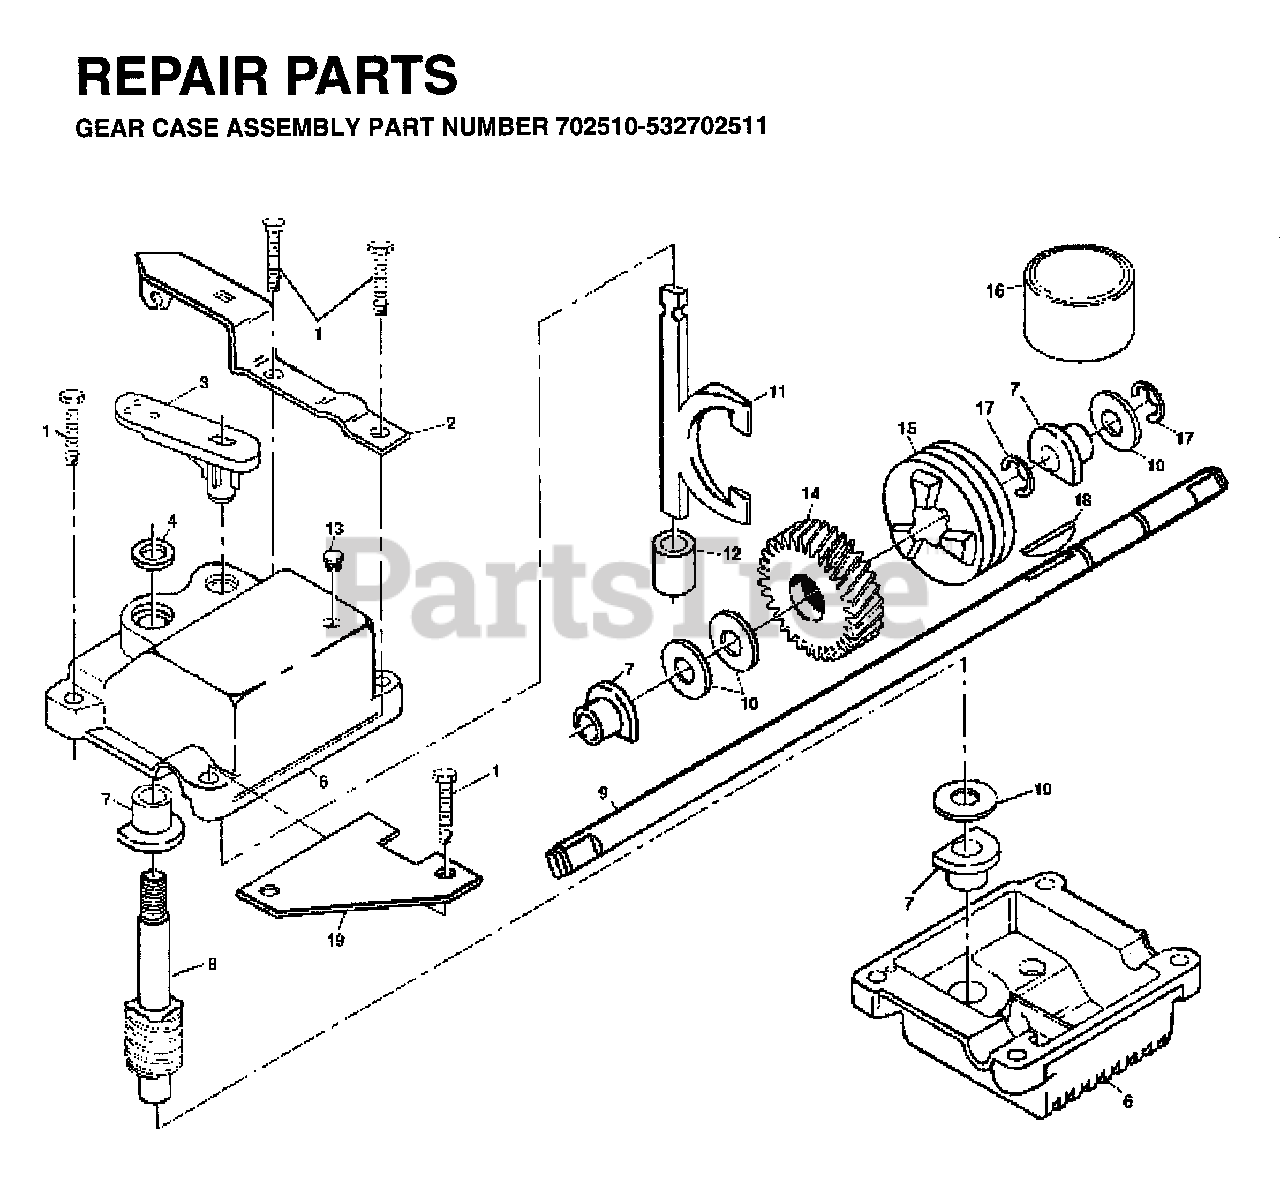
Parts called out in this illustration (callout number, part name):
1	SCREW
2	BRACKET
6	GEAR CASE
8	WORM SHAFT
9	DRIVE SHAFT, 20-5/8"
10	THRUST WASHER
11	YOKE CLUTCH
14	GEAR.HELICAL
15	CLUTCH JAW
16	RP GREASE
18	HI PRO KEY
19	BRACKET SPRING
